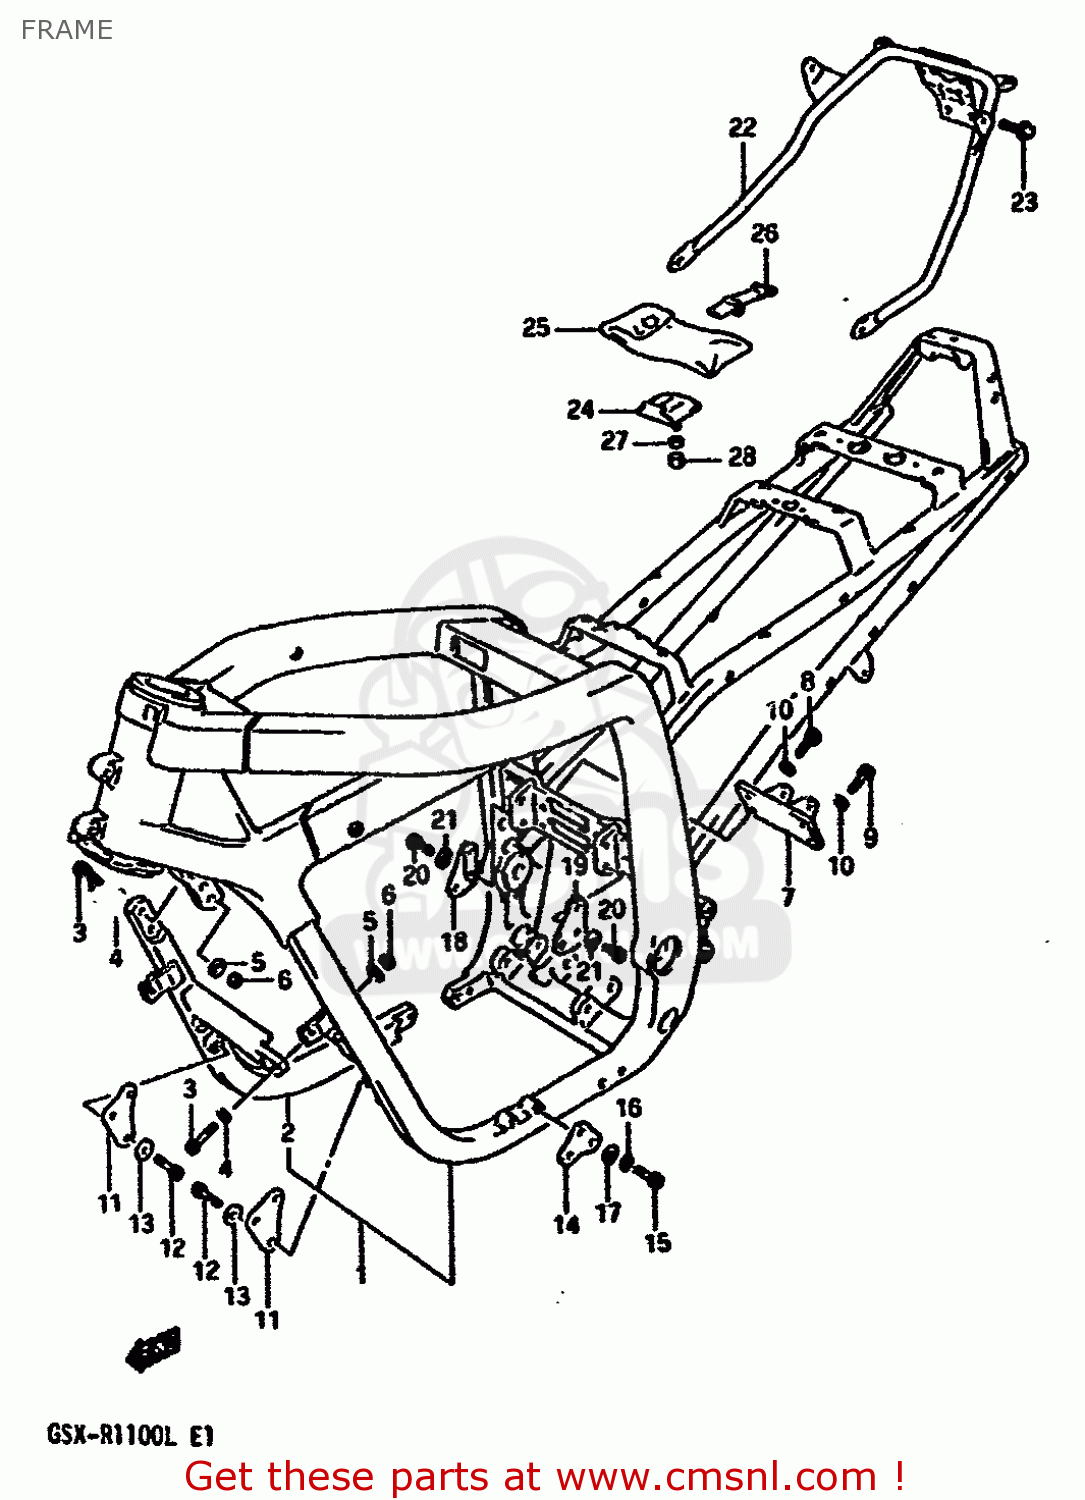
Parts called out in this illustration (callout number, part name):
1	FRAME
2	TUBE COMP,FRAME DOWN,RIGHT
3	BOLT, LH
4	WASHER (10.1X21X2.3)
5	WASHER
6	NUT
7	BRACKET,REAR CUSHION UNIT
8	BOLT 10X27
9	BOLT, LH
10	WASHER
11	PLATE,ENGINE MOUNTING
12	BOLT, FRONT LH
12A	WASHER,LOCK,8.
13	WASHER (8.2X20X1.6)
14	PLATE,ENGINE MOUNT NO.2
15	BOLT, FRONT LH
16	WASHER,LOCK
17	WASHER (8.2X20X1.6)
18	PLATE,ENGINE MOUNT NO.3,R
19	PLATE,ENGINE MOUNTING NO
20	BOLT(8X22)
20A	WASHER,LOCK,8.
21	WASHER (8.2X20X1.6)
22	GRIP COMP,REAR
23	BOLT
24	HOLDER,TOOL
25	TOOL SET
26	BAND
27	WASHER
28	NUT 6MM
